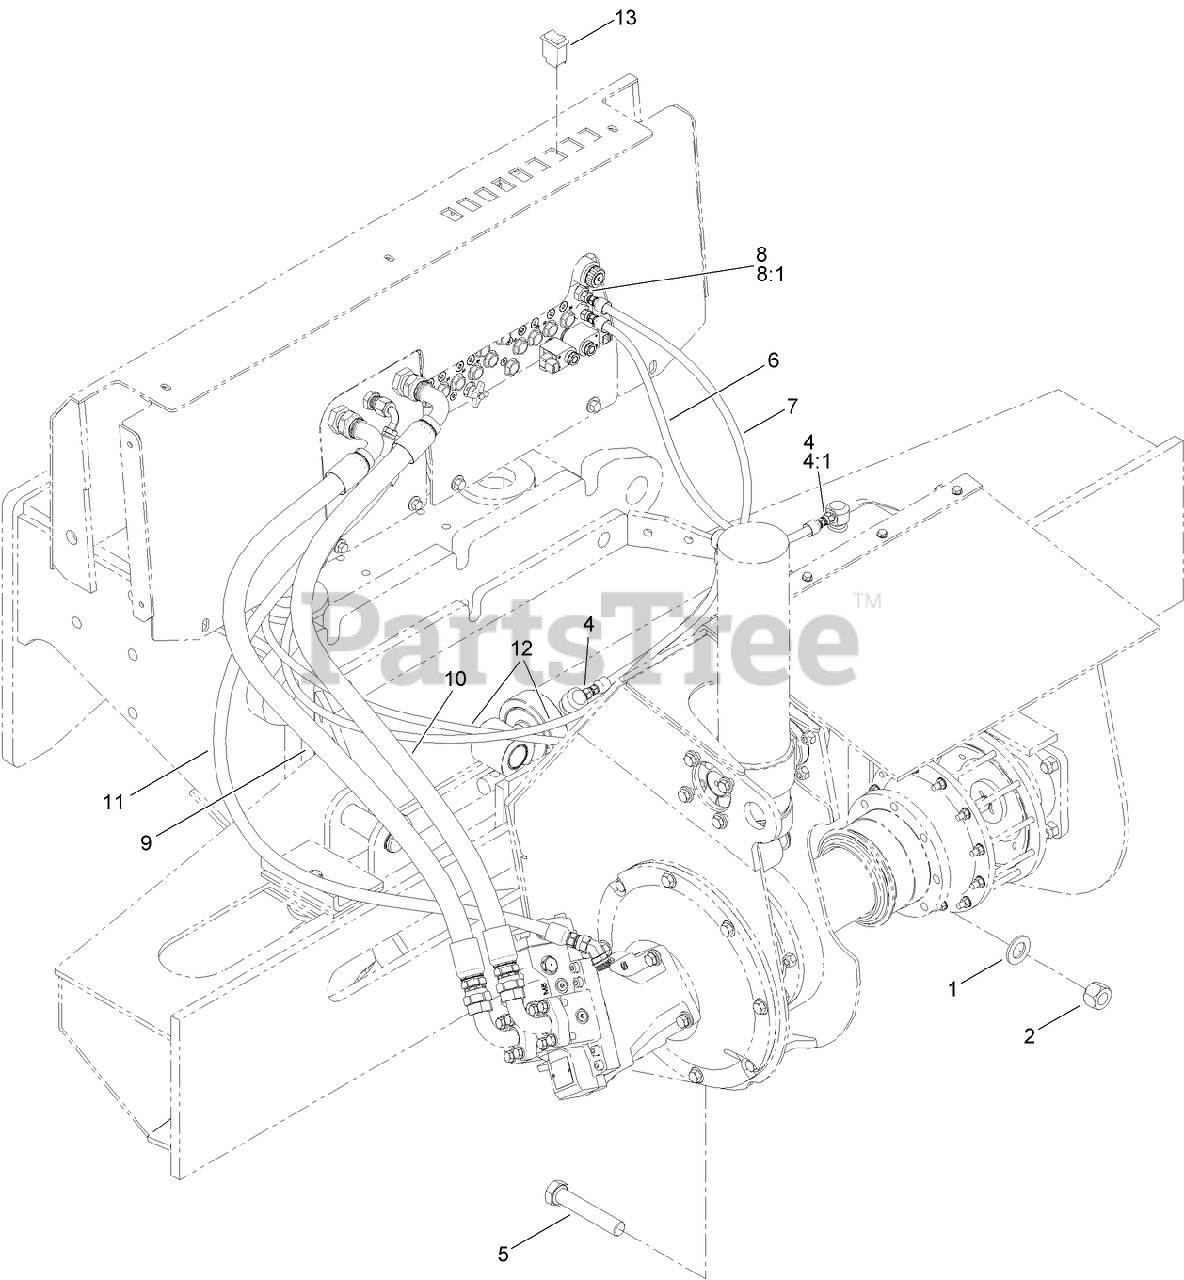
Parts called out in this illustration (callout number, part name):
4	ADAPTER-HYD
4:1	O-RING
5	SCREW-HH
6	HYD HOSE ASM, HP
7	HYD HOSE ASM, HP
8	CONNECTOR
8:1	O-RING
9	HOSE ASM
10	HOSE ASM
11	HYD HOSE ASM, LP
12	HYD HOSE ASM, HP
13	SWITCH-ROCKER, 2 POLE
